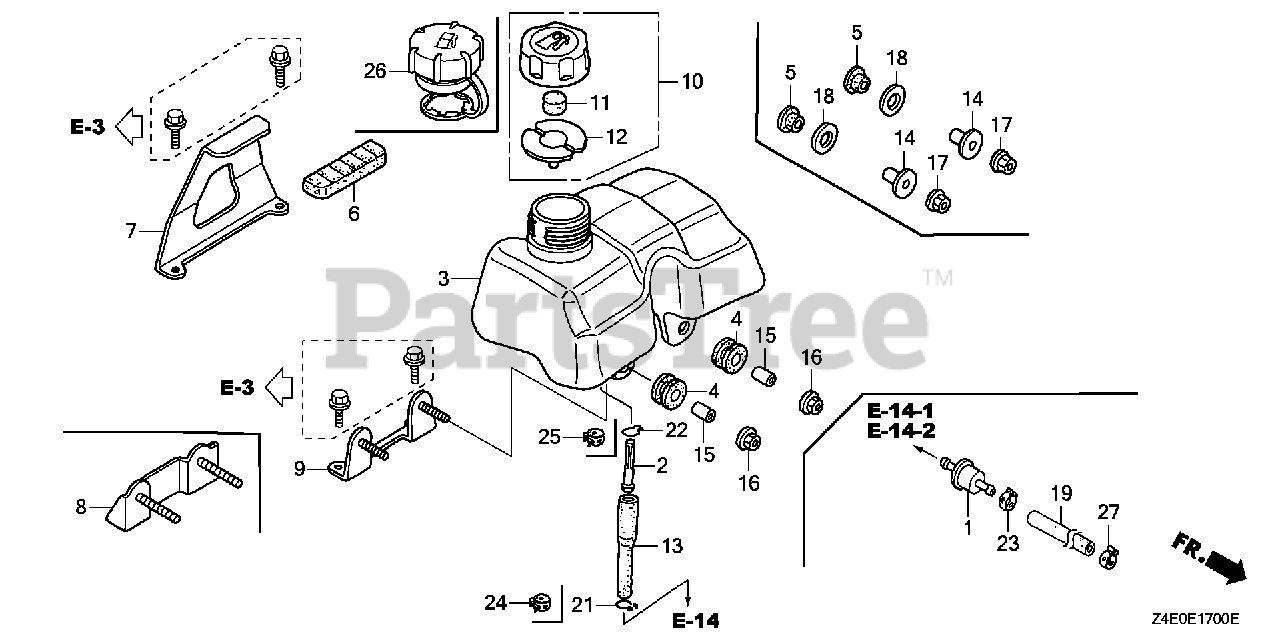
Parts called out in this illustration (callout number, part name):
2	FILTER, FUEL
3	TANK, FUEL
4	RUBBER A, TANK MOUNTING
6	RUBBER B, TANK MOUNTING
7	STAY A, FUEL TANK
9	STAY B, FUEL TANK
10	CAP ASSY., FUEL TANK
11	SPONGE, FUEL CAP BREATHER
12	GASKET, FUEL CAP
13	TUBE, FUEL
13	TUBE, FUEL (FKM)
15	COLLAR, IGNITION COIL SETTING
16	NUT, FLANGE (6MM)
21	CLIP, TUBE (B8)
22	CLIP, TUBE (B10)
24	CLIP, TUBE (D8)
25	CLIP, TUBE (10.5MM)
26	CAP ASSY., FUEL TANK
